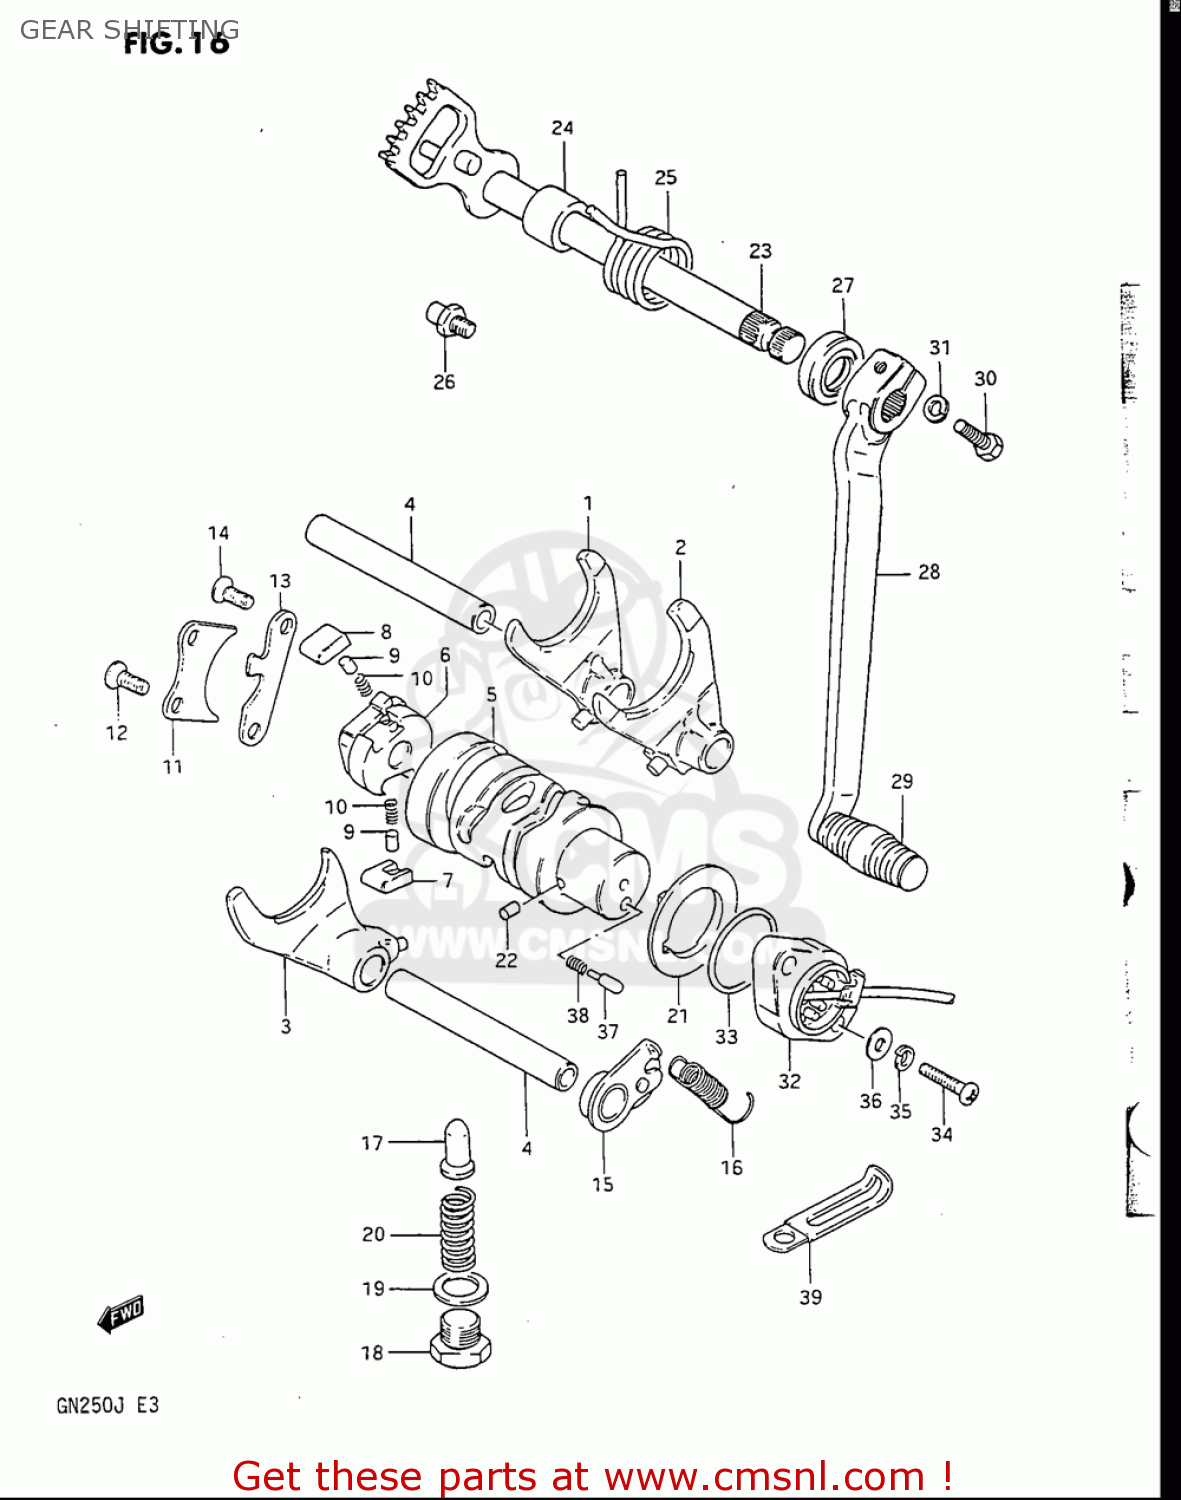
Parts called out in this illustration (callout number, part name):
1	FORK,GEAR SHIFT NO.1
2	FORK,GEAR SHIFT NO.2
3	FORK,GEAR SHIFT NO.3
4	SHAFT,GEAR SHIFT FORK
6	GEAR,GEAR SHIFT CAM DRIVEN
7	PAWL,GEAR SHIFT NO.1
8	PAWL,GEAR SHIFT NO.2
9	PIN(5X8)
10	SPRING
11	LIFTER,GEAR SHIFT POLE
12	SCREW
13	GUIDE,GEAR SHIFT CAM
14	SCREW
15	STOPPER,GEAR SHIFT CAM
16	SPRING
17	STOPPER,GEAR SHIFT CAM NO.2
18	PLUG(14X12)
19	GASKET(14X19.2X2) (NAS)
20	SPRING
21	PLATE,GEAR SHIFT CAM STOPPER
22	PIN
23	SHAFT,GEAR SHIFT
24	SPACER(12X20X15.3)
25	SPRING
26	STOPPER,GEAR SHIFT ARM
27	SEAL,OIL (12X22X9)
28	LEVER ASSY,GEAR SHIFT
29	RUBBER,GEAR SHIFT PEDAL
30	BOLT
31	WASHER,LOCK
32	TERMINAL BASE ASSY,GEAR SHIFT
33	O RING(D:2.4,ID:26.2)
34	SCREW
35	LOCK,WASHER
36	WASHER
37	PIN(5X15.5)
38	SPRING
39	CLAMP(L:65)
